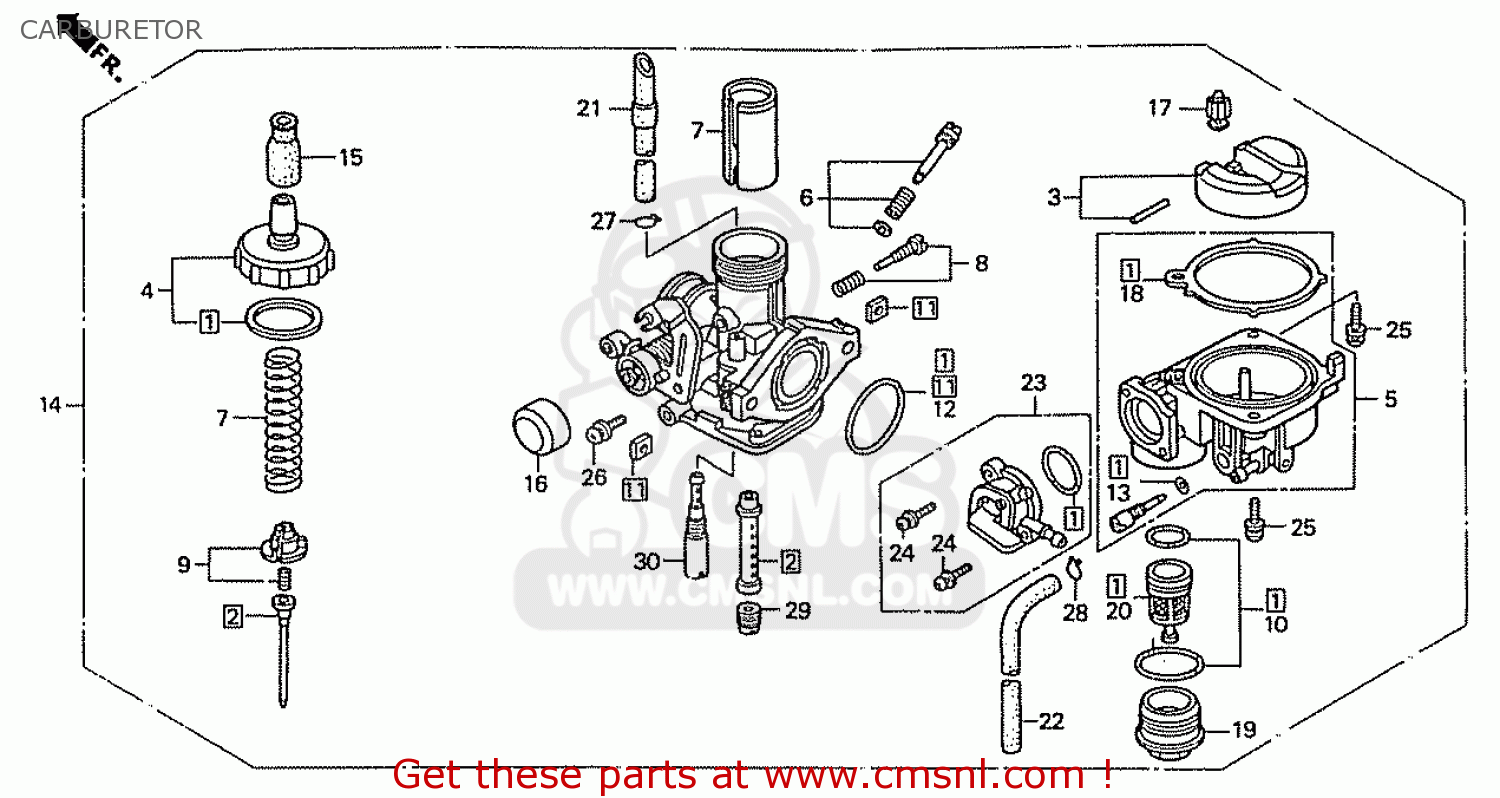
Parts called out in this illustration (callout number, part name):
1	GASKET SET
2	NEEDLE SET,JET
3	FLOAT SET
4	TOP SET (TDM)
5	CHAMBER SET FLOAT
6	SCREW SET
7	VALVE SET,THROTTL (TDM)
8	SCREW SET
9	PLATE SET VALVE
10	GASKET SET
11	NUT SET,SQUERE
12	O-RING,2.4X25
13	O-RING,1.3X4.3
14	CARBURETOR ASSY
15	SEALING CAP,CABLE
16	CAP,CHOKE DUST
17	VALVE,FLOAT
18	GASKET,FLOAT CHAM
19	CUP,FUEL STRAINER
20	FILTER CUP
21	TUBE AIRVENT
22	TUBE,OVERFLOW
23	COCK BODY SET
24	SCREW WASH 3X12
25	SCREW-WASHER,4X18
26	SCREW WASH 5X10
27	CLIP B1 8,TUBE
28	CLIP B1 6.5 TUBE
29	JET,MAIN #75
30	JET COMP,#42X#42
